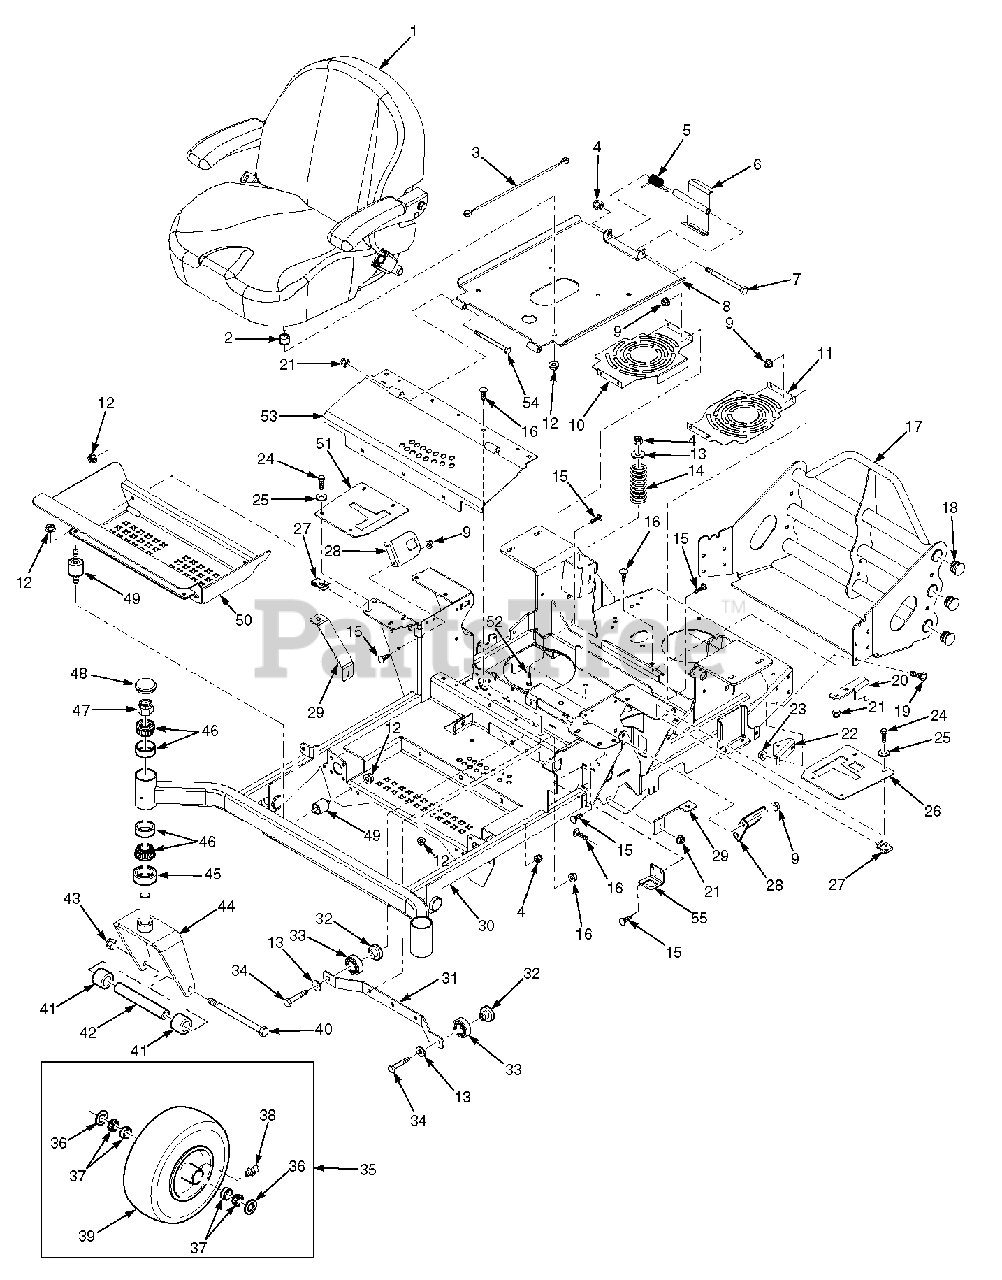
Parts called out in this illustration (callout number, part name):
1	Seat Assembly
2	Spacer
3	Cable, Seat Stop
4	Nut, Elastic Stop 3/8-16
5	Spring, Seat Latch
6	Weldment, Seat Latch
7	Bolt, Hex Head 3/8-16 x 6"
8	Seat Plate Weldment
9	Nut, Serrated Flange 1/4-20
10	Fan Cover, RH
11	Fan Cover, LH
12	Nut, Serrated Flange 5/16-18
13	Flatwasher, 3/8-.391 x .938 x .105
14	Spring, Seat
15	Bolt, Carriage 1/4-20 x 1"
16	Bolt, Carriage 5/16-18 x 3/4"
17	Bumper Weldment
18	Plug, Bumper Tube
19	Bolt, Hex Head 3/8-16 x 1"
20	Anti-Rotation Bracket
21	Nut, Elastic Stop 5/16-18
22	Bracket, Dump Valve
23	Nut, Serrated Flange 3/8-16
24	Bolt, Hex Head 1/4-20 x 1"
25	Flatwasher, 1/4-.312 x .750 x .065
26	Control Plate w/Decal, LH
27	U-Nut, 1/4-20
28	Bracket, Switch Mount
29	Bracket, Tank Mount, SFZ52
29	Bracket, Tank Mount, SFZ61
30	Mainframe Assy., w/Decals - SFZ52
30	Mainframe Assy., w/Decals - SFZ61
31	Support, Deck Guide
32	Spacer, Bearing
33	Bearing
34	Bolt, Hex Head 3/8-16 x 2-1/2"
35	Wheel Assembly
37	Bearing
38	Fitting, Grease
39	Tire, 13 x 5-6
40	Bolt, Hex Head 1/2-13 x 7-1/2"
41	Spacer, Caster Wheel
42	Sleeve, Caster Wheel
43	Nut, Elastic Stop 1/2-13
44	Yoke Weldment
45	Seal, 2" OD x 1.625 ID
46	Bearing Set
47	Nut, Elastic Stop 1"-14
48	Grease Cap
49	Rubber Isolator
50	Footplate Weldment, SFZ52
50	Footplate Weldment, SFZ61
51	Control PLate w/Decal, RH
52	Bolt, Carriage 3/8-16 x 1-1/4"
53	Deck Lift Cover w/Decal, SFZ52
53	Deck Lift Cover w/Decal, SFZ61
54	Bolt, Hex Head 5/16-18 x 3-3/4"
55	Switch Bracket
